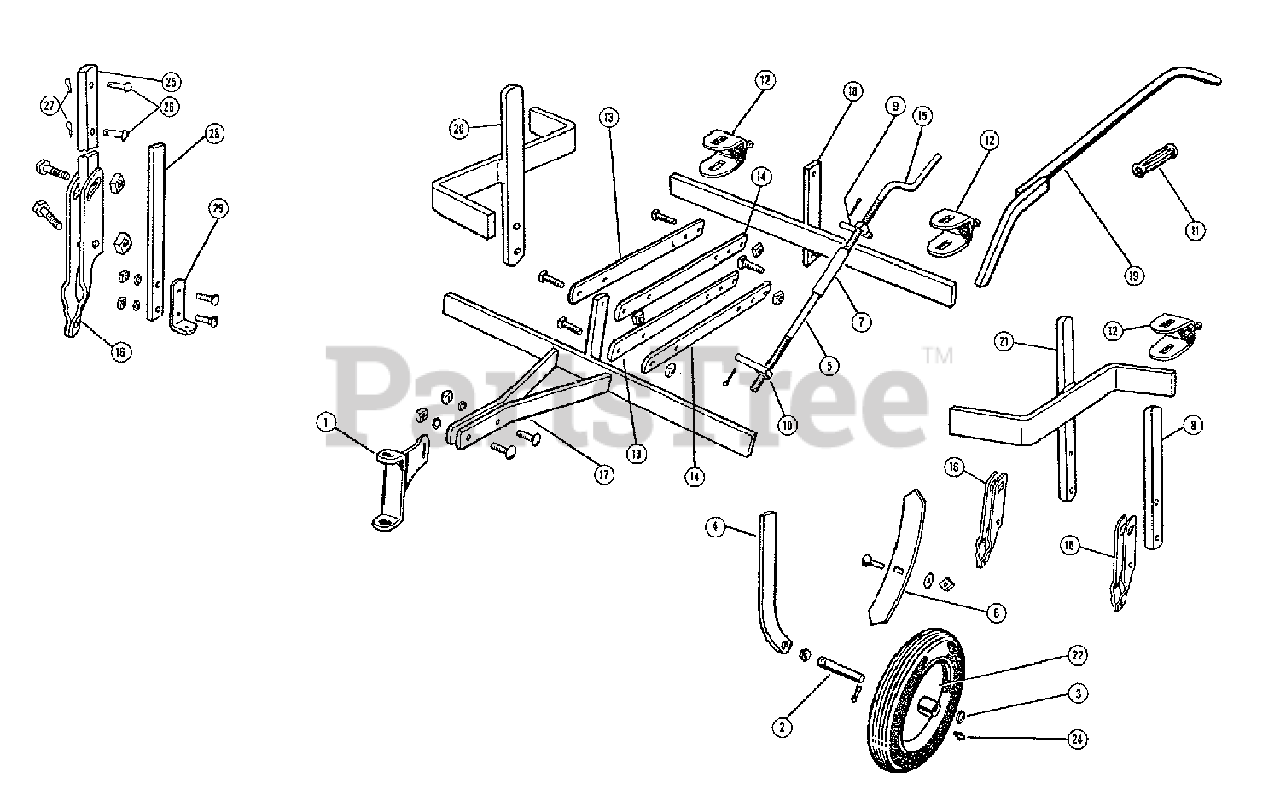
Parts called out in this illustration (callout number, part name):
1	DRAW BAR, End
2	WHEEL SPINDLE, Gauge
3	WHEEL WASHER, Gauge
4	WHEEL STANDARD, Gauge
5	LOWER SCREW MEMBER
6	CULTIVATOR, Steel w/ Bolt
7	COUPLING, Adjustment
8	TOOL STANDARD, Short
9	NUT, Upper Adjustment
10	NUT, Lower Adjustment
11	HANDLE GRIP, Rubber
12	CLAMP, Shank
13	PARALLEL BAR, Right, Unthreaded
14	PARALLEL BAR, Left, Threaded
15	UPPER SCREW MEMBER
16	TOOL HOLDER ASSEMBLY
17	DRAW BAR ASSEMBLY
18	TOOL BAR ASSEMBLY
19	TOOL HANDLE ASSEMBLY
20	R.H. TOOL FRAME ASSEMBLY
21	L.H. TOOL FRAME ASSEMBLY
22	WHEEL, Complete w/ Juvenile Tires 10 x 2.0
27	CLIP, Spring
28	TOOL STANDARD
29	TOOL HOLDER
